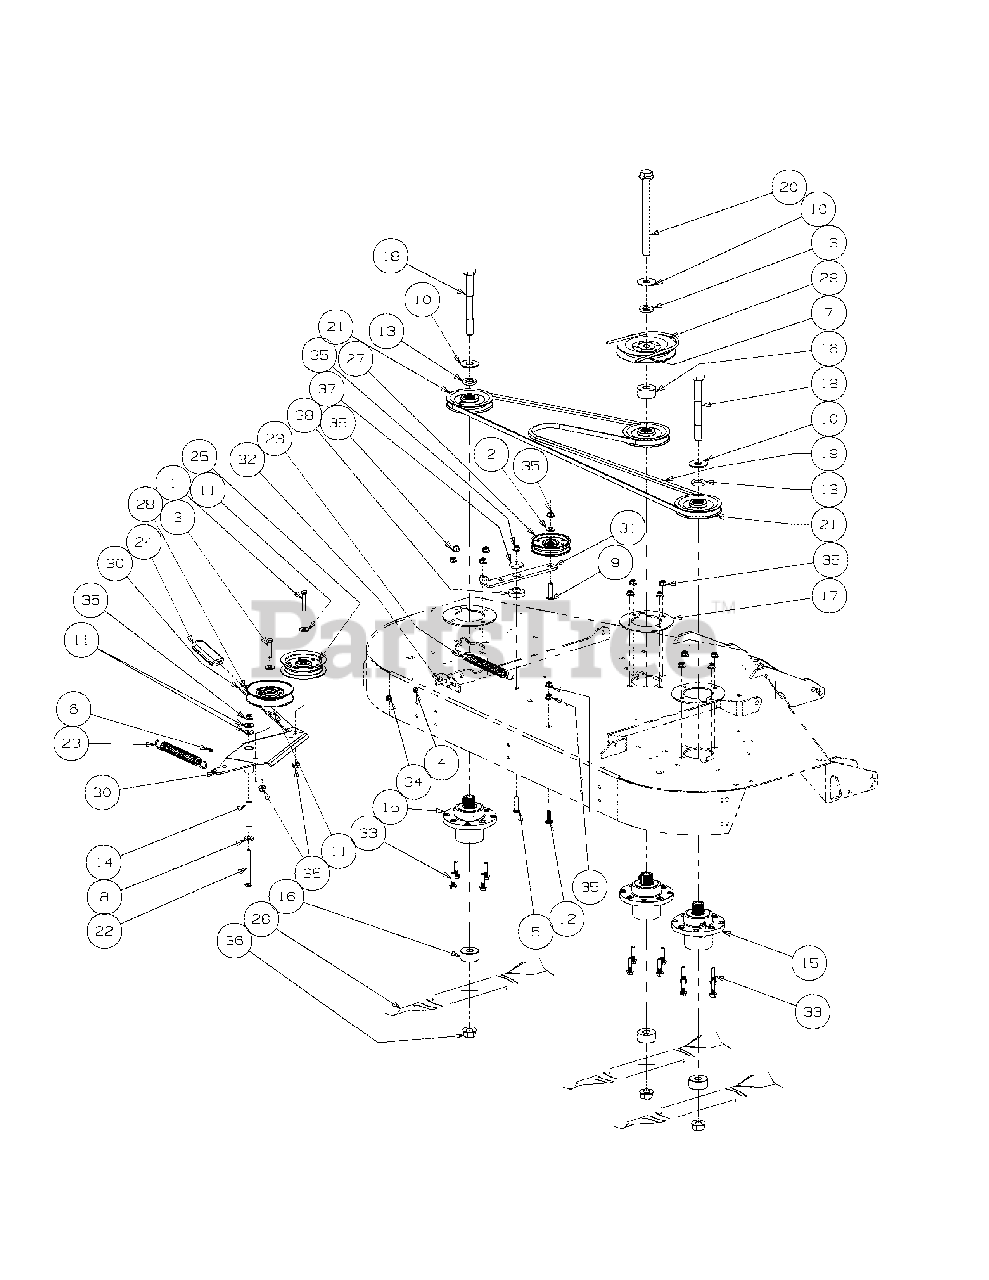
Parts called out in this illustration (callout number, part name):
1	Hex Cap Screw, 3/8-16 x 2.00
2	Flat Washer, 3/8
3	Hex Cap Screw, 3/8-16 x 1-3/4
4	Nut, 5/16-18, Hex
5	Carriage Bolt, 3/81-6 x 1-1/2
6	Grease Fitting, 1/4-28 x 3/16
7	V-Belt, B-Section, BK90
8	Idler Washer
9	Hex Carriage Screw, 3/8-16, 1.75
10	Flat Washer, .781 ID 2.00 OD, .105
11	Flat Washer, .406 ID, 1.0 OD, .105
12	Carriage Screw, 3/8-16 x 1.25
13	Spacer .812 ID x .268 LG
14	Spacer, .39 ID x .625 OD x 2.75
15	Aluminum Spindle Assembly
16	Spacer, .760 ID x 2.00 OD x 1.1
17	Aluminum Spindle Support Plate
18	Hex Cap Screw, 3/4-16, 7.00
19	V-Belt, A Section x 122.3
20	Hex Cap Screw, 3/4-16, 9.00
21	V-Pulley, 5.00 OD
22	Carriage Bolt, 3/8-16 x 4.00
23	Extension Spring, .94 x OD x 7.57
24	Grip, 1.0 x 3.2 x .25
25	Idler Pulley, 4.06 OD
26	Hi-Lift Blade, 21.0, 0.756 ID
27	Flat Pulley with Flanges
28	Idler Pulley, 5.06 OD
29	V-Pulley, 6.38 OD x .760 ID
30	Idler Arm Assembly includes:
30	Bearing
32	Carriage Bolt, 5/16-18 x 1.50
33	Bolt, 3/8-16 x 1.5
34	Nut, 5/16-18, Nylon Flange Lock
35	Nut, 3/8-16, Nylon Flange Lock
36	Flange Hex Nut, 3/4-16
37	Washer, .390 x 1.500 x .134
38	Shoulder Screw, .854 x .280
